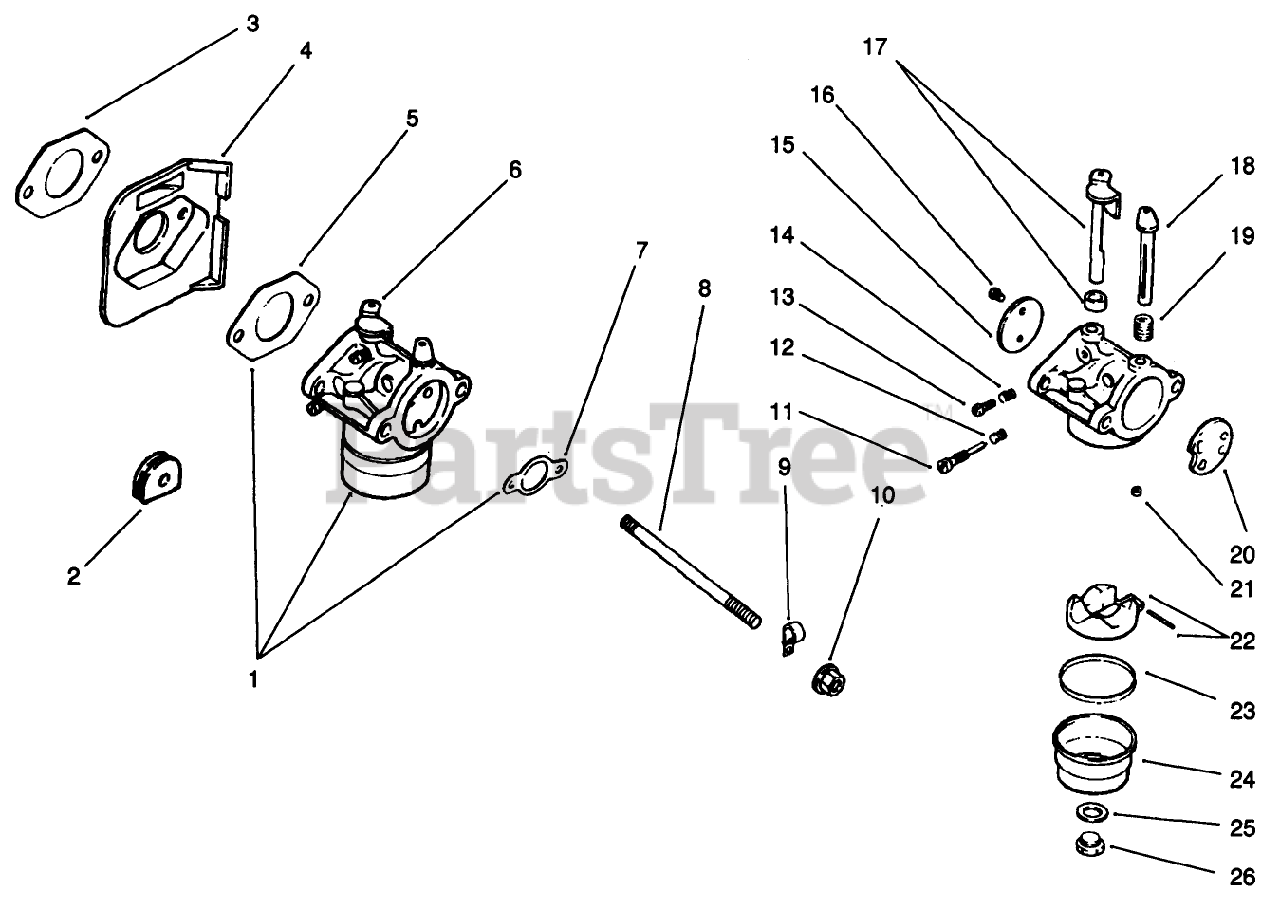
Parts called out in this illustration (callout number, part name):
1	Kit-Carb INCL 4/6/21 -36 (Only On: 72042,72043,72062,72063)
2	Grommet (Only On: 72042, 72063, 72062, 72043)
3	Gasket-Carburetor (Only On: 72042, 72063, 72062, 72043)
4	Deflector-Heat (Only On: 72042,72043,72062,72063)
5	Carburetor Assembly (Incl Ref. #11-26)
6	Gasket-Carburetor (Only On: 72042, 72063, 72062, 72043)
7	Gasket-Air Cleaner (Only On: 72042, 72043, 72062, 72063)
8	Stud M6x1.0x110 (Only On: 72042,72043,72062,72063)
11	Needle-Idle Fuel Adjust (Only On: 72042, 72063, 72062, 72043)
12	Spring-Idle Fuel (Only On: 72042, 72063, 72062, 72043)
13	Screw-Idle Speed Adjust (Only On: 72042,72043,72062,72063)
14	Spring-Idle Fuel (Only On: 72042, 72063, 72062, 72043)
15	Plate-Throttle (Only On: 72042,72043,72062,72063)
16	Screw-Throttle Plate (Only On: 72042,72043,72062,72063)
17	Shaft-W/Lever Seal (Only On: 72042, 72063, 72062, 72043)
18	Shaft-Choke (Only On: 72042. 72063, 72062, 72043)
19	Spring-Choke Return (Only On: 72042,72063, 72062, 72043)
20	Plate-Choke (Only On: 72042, 72063, 72062, 72043)
21	Jet-Main
22	Kit-Float (Only On: 72042,72043,72062,72063)
23	Gasket-Bowl (Only On: 72042,72043,72062,72063)
24	Bowl-Fuel (Only On: 72042, 72063, 72062, 72043)
25	Gasket-Bowl Screw (Only On: 72042, 72063, 72062, 72043)
26	Screw-Fuel Bowl (Only On: 72042, 72063,72062, 72043)
